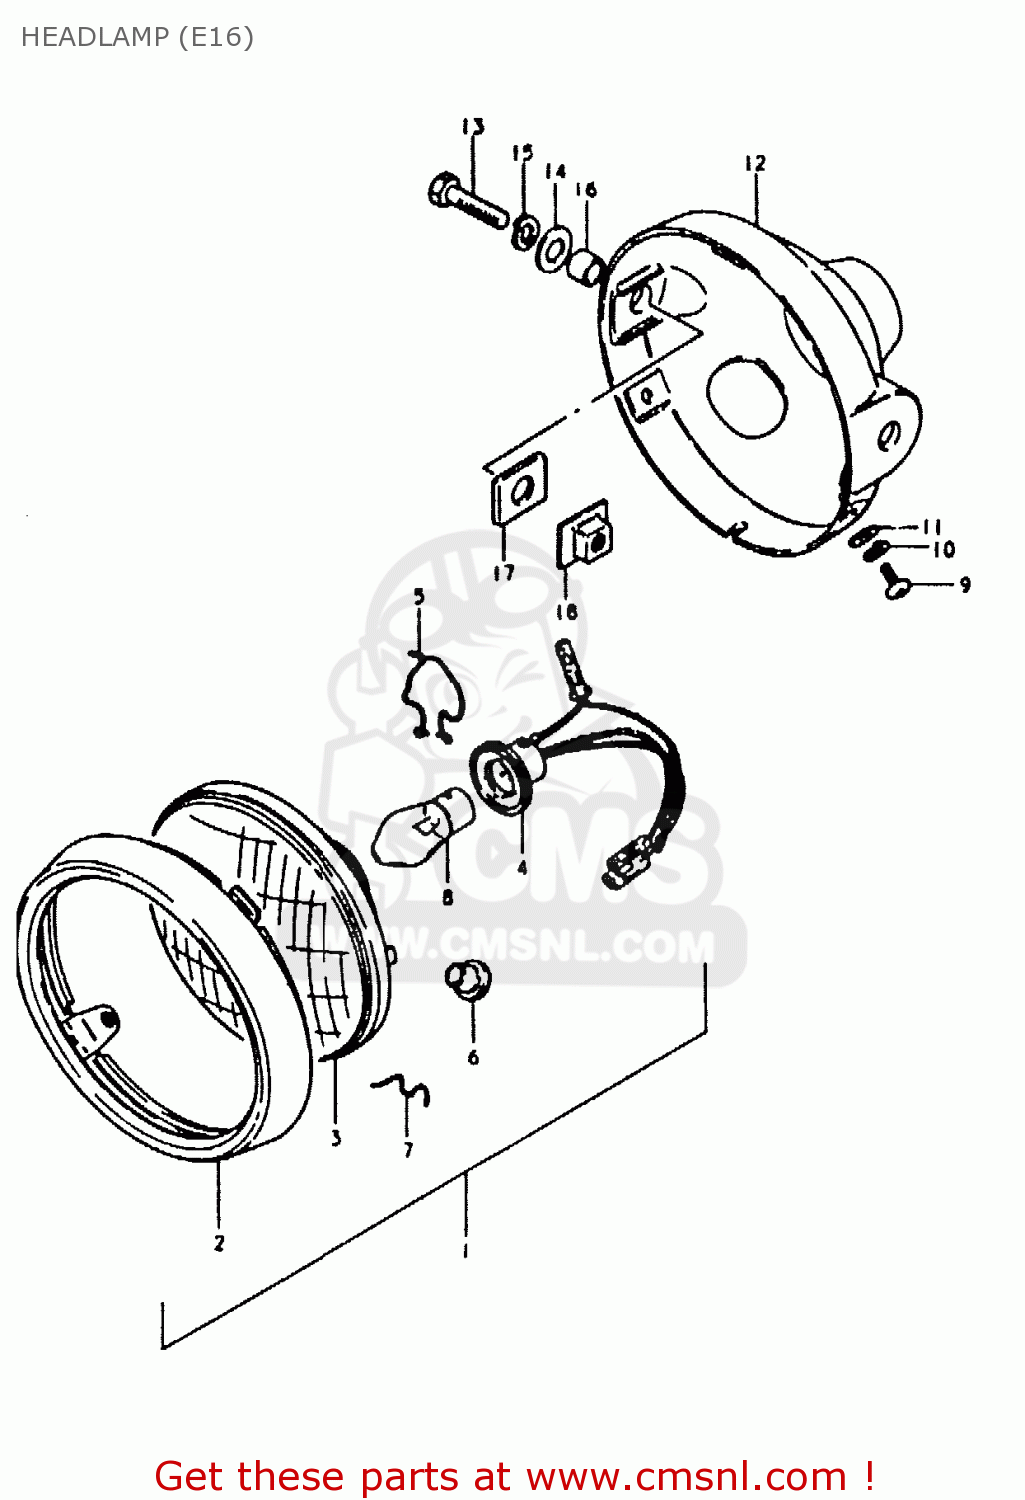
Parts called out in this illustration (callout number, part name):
1	HEADLAMP ASSY
2	RIM
3	UNIT
4	SOCKET,HEADLAMP
5	CLAMP,HEADLAMP
6	CAP,HOLE
7	SPRING
8	BULB (6V,25/25W)
9	SCREW
10	LOCK WASHER
11	WASHER
12	HOUSING,HEADLAMP
13	BOLT
14	WASHER
15	LOCK WASHER
16	SPACER (8.8X12X7)
17	CUSHION
18	PLATE,HEADLAMP HOUSING
